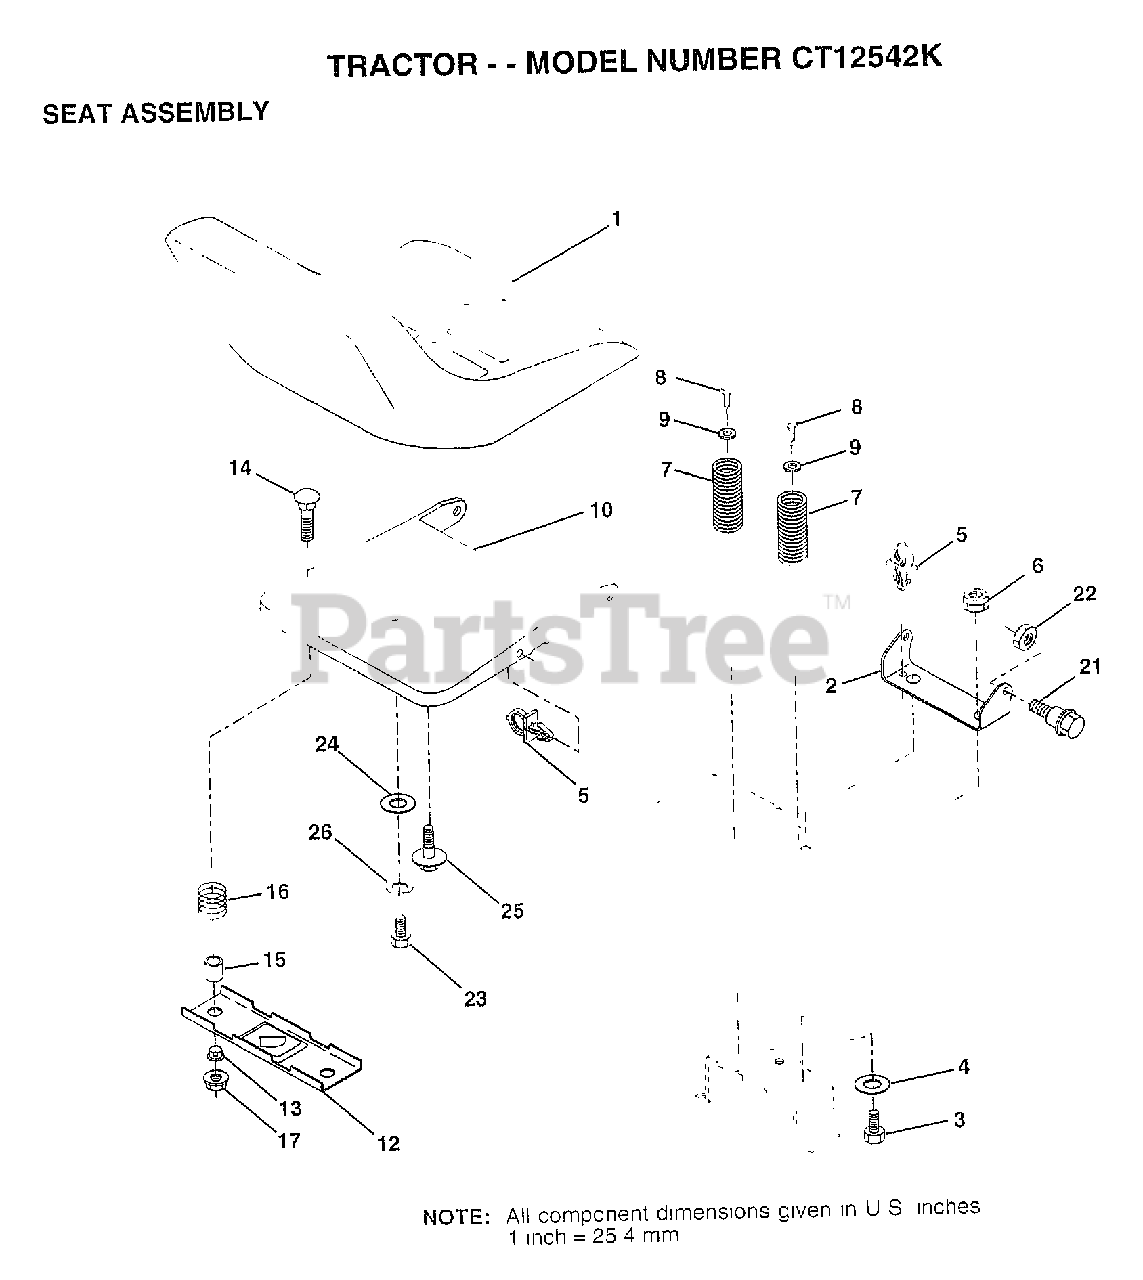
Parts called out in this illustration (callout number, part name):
2	BRACKET PVT SEAT
3	BOLT
4	WASHER PM
5	CLIP.PUSH-IN.HING
6	NUT
7	SPRING COMPRESSIO
8	SCREW GTV
9	WASHER
10	PAN-SEAT
12	BRKT SWITCH
13	BUSHING
15	SPLIT SPACER
16	SPRING
21	"BOLT,SHOULDER"
22	NUT
23	BOLT
24	WASHER
25	"BOLT,SHOULDER"
26	LOCKWASHER
